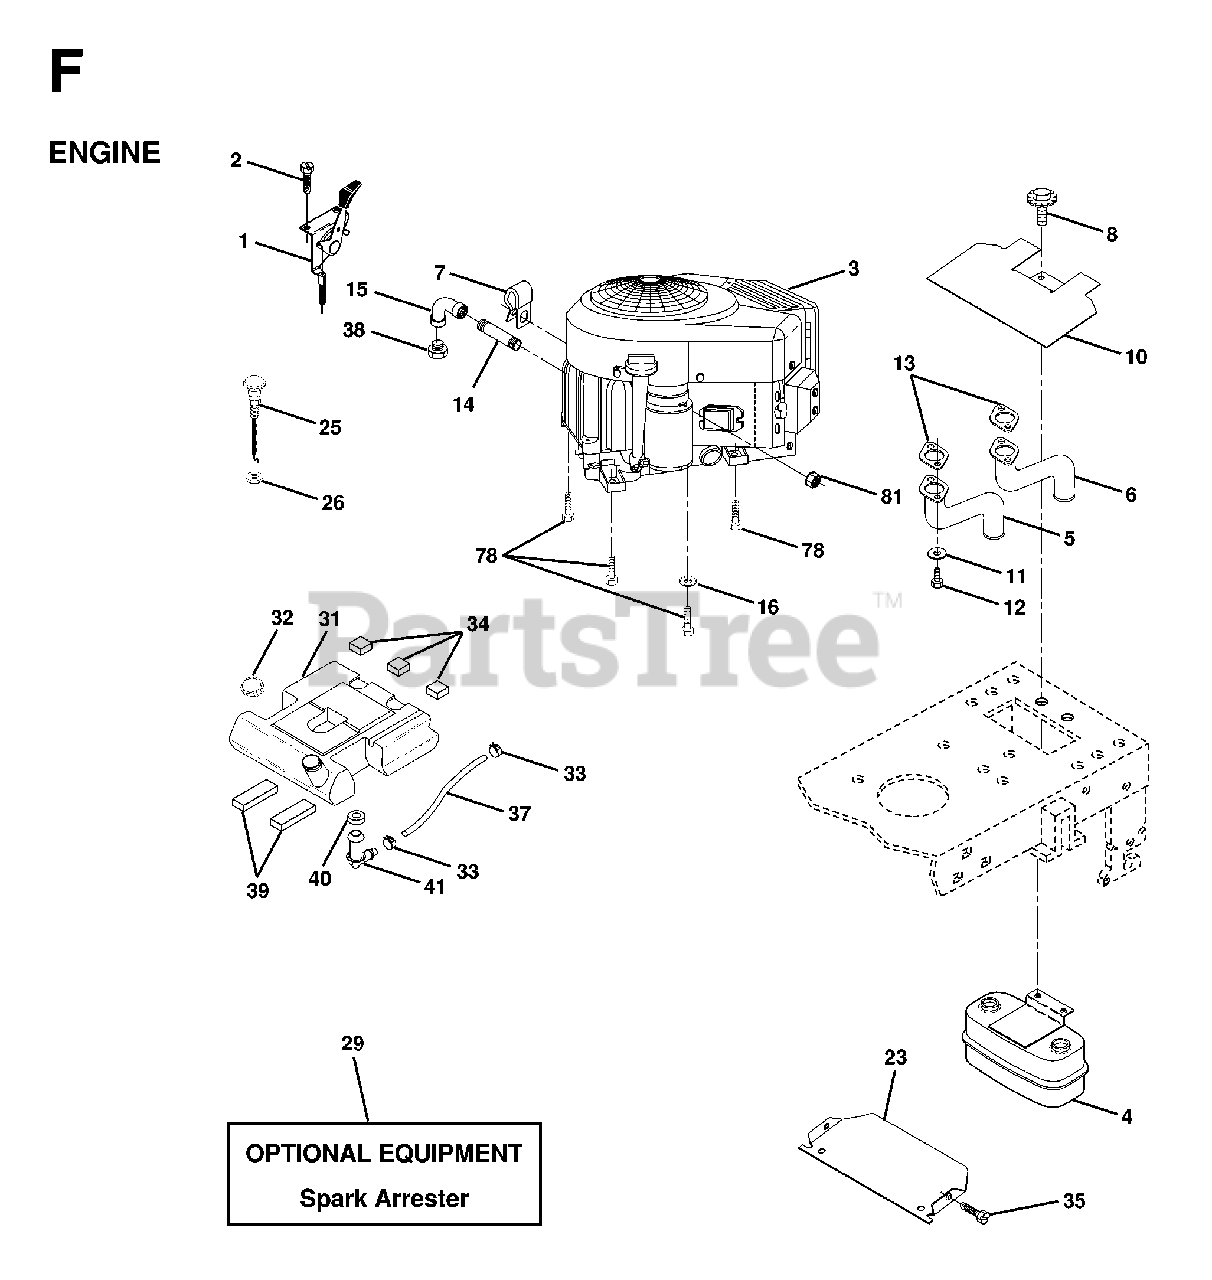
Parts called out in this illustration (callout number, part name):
1	CONTROL THROTTLE 36"
2	SCREW LT
4	MUFFLER.TWIN.CYL.LOW.TONE
5	TUBE ASSY EXH LH
6	TUBE ASSY EXH RH
8	BOLT HEX WASHER HD 5/16-18
10	SHIELD HEAT LT
14	PIPE NIPPLE LT
15	ELBOW
16	LOCKWASHER
23	SHIELD HEAT
25	CONTROL, CHOKE
26	NUT KEPS 3/8 - 24 UNF
29	ARRESTER SPARK (OPTIONAL)
31	FUEL TANK
32	FUEL CAP
33	HOSE CLAMP
34	PAD-SPACER LT
35	SCREW
39	PAD IDLER TI
40	BUSHING OUTLET T
41	STEM FUEL TANK
78	SCREW
81	NUT FLANGE 1/4-20 STARTER NUT
